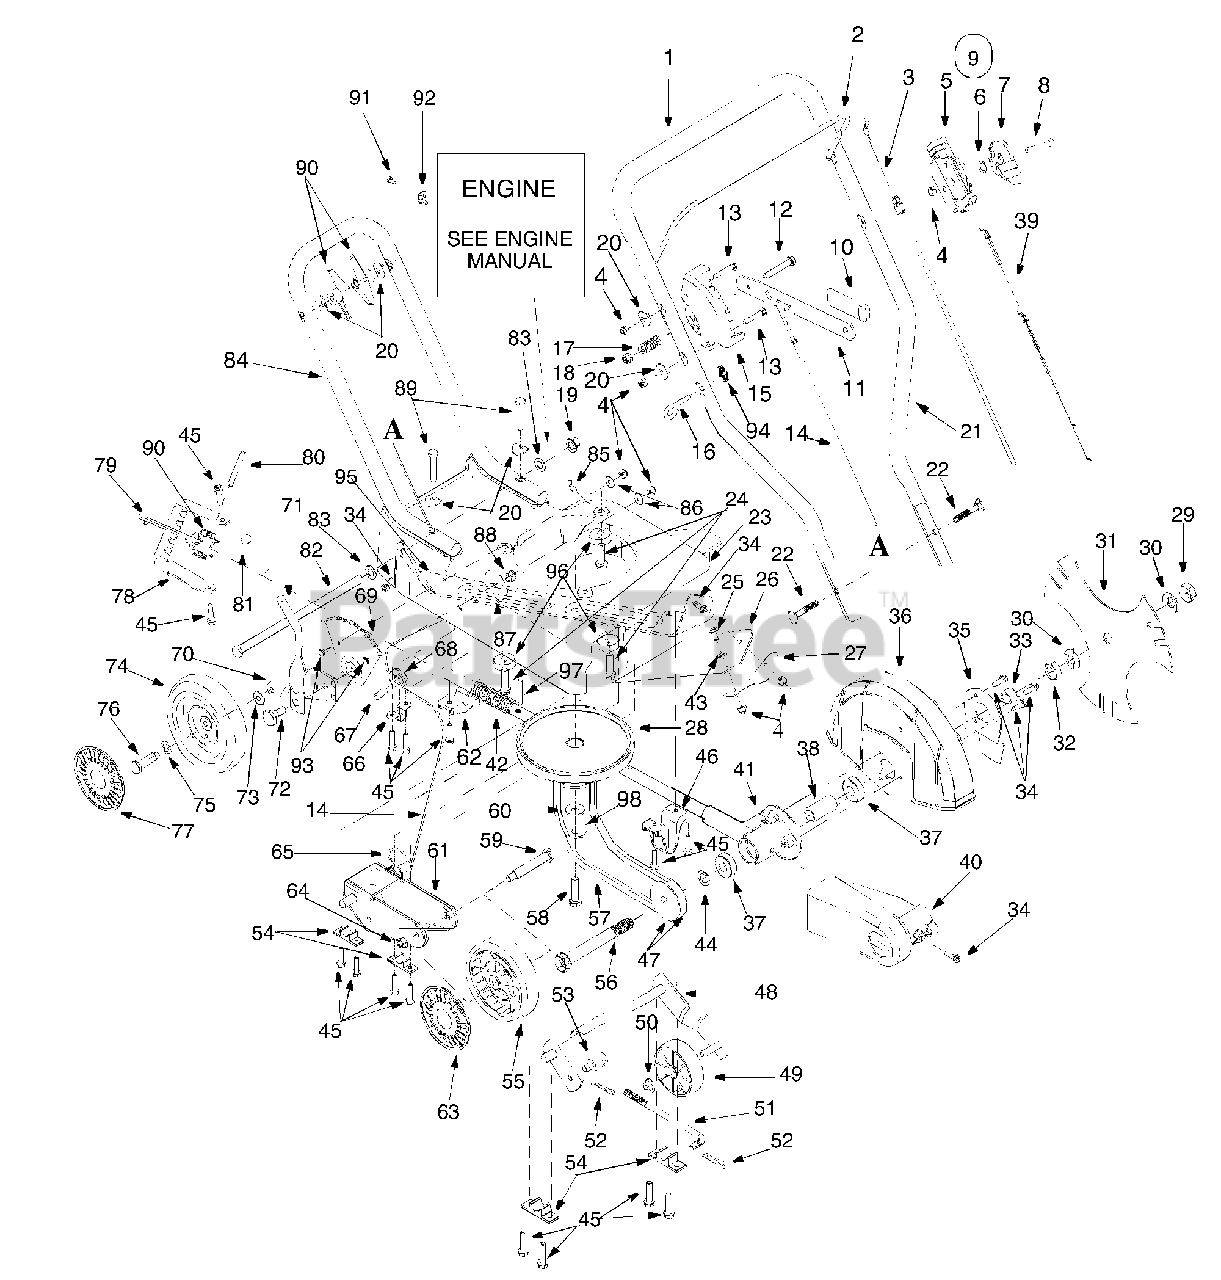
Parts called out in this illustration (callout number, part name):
3	Control Cable
4	Hex Lock Nut 1/4-20 Thd.
5	Throttle Hsg.
6	Curved Washer .663 x .980 x .014
7	Throttle Lever
8	Screw Oval C-Sunk 1/4-20 x 1.81 Lg.
9	Throttle Comp.
10	Grip - Black
12	Hex Screw 5/16-18 x 2.0 Lg.
13	Carriage Bolt 1/4-20 x 1.50 Lg.
15	Depth Bracket
16	Eye Bolt 1/4-20
17	Compression Spring .550 O.D. x 1.3
18	Hex Lock Nut 5/16-18
19	Push Cap x 1/2 Rod
20	Washer .320 ID x .93 O.D.
23	Edger Base Ass'y
24	Tapp Screw w/Hex Lock Wash 3/8-16
25	Hex Screw 1/4-20 x .50 Lg.
26	Discharge Shield Deflector
27	Deflector Keeper
28	Engine Pulley
29	Hex Jam Nut 5/8-18
30	Bell Washer .63 I.D. x 1.25 O.D. x .18
32	Hex Jam Nut 5/8-18
33	Spacer .628 x .875 x .545 Lg.
34	Hx Scr. w/Wash.: TT: 1/4-20 x .750 Lg.
37	Ball Bearing .62 I.D. x 1.38 O.D. x .4
38	Spacer .628 x .875 x 1.818 Lg.
39	Throttle Cable
41	Spindle w/Insert
42	Compression Spring: Arbor
43	Flat Washer .283 I.D x .75 O.D. x .030
44	Flat Washer .635 I.D. x .93 O.D. x .06
45	Hex Screw w/Wash 1/4
46	Front Rod Handler
47	Pulley
50	Push Cap x 3/8 Rod
52	Cotter Pin .072 x 1.12
53	Ferrule 5/16-24 x .312
54	Black Bushing .515 Dia x .62
55	Wheel 7" x 2" Link w/BB
56	Hex Bolt 5/8-18 x 5.25 Lg.
57	V-Belt
58	Hex Screw: 3/8-24 x 1.50 Lg.
59	Shoulder Screw .500 x 2.62: 3/8-16
60	Bell Wash. .396 I.D. x 1.140 O.D. x .095
61	Front Wheel Brkt Ass'y.
62	Rear Rod Handler
63	Hubcap: Spoke w/Hole Grey
64	Jam Lock Nut 3/8-16
65	Torsion Spring
68	Cable Roller Pulley
69	Index Plate
71	Spring Lever
72	Shoulder Bolt .500 x .434 Lg.
73	Bell Wash. .401 I.D. x .870 O.D. x .063
74	Wheel - 8" x 2" Link Grey w/BB
75	Wave Washer .510 I.D. x .750 O.D.
76	Shoulder Bolt .498 x 1.445: 3/8-16
77	Hubcap: Radial Spoke Grey
78	Tilt Bracket
79	Adj. Lever Ass'y
80	Pin 1/4 x 2.0" Lg.
83	Flat Wash. .531 I.D. x .875 O.D. x .06
86	Flat Wash. .285 I.D. x 1.25 O.D. x .06
87	Flat Wash. .406 I.D. x 1.92 O.D. x .06
88	Hex Lock Nut 3/8-16
89	Hex Screw 5/16-18 x 1.75 Lg.
90	Torsion Spring
90	Wing Knob Nut 5/16-18
91	Hex Scr. w/Wash. :T: #10-32 x .625 Lg.
92	Clamp B&S Throttle
93	Screw Std. 1/4-20 x .75 Lg.
98	Flat Washer .38 ID x 1.38 OD x .125
